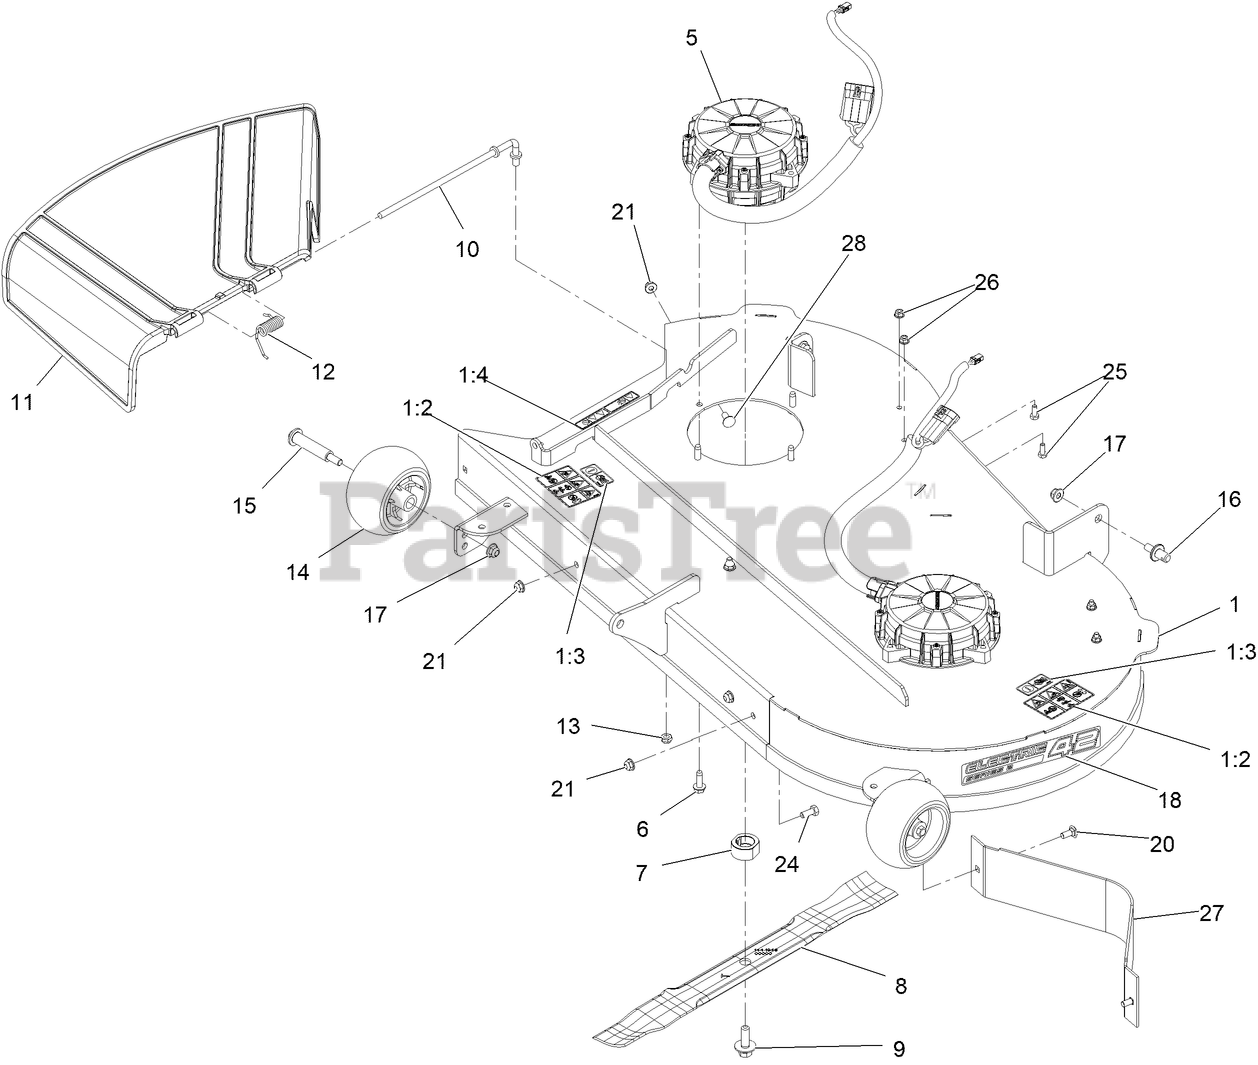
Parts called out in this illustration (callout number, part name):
1	42 In Deck And Decal ASM
1:2	DECAL-DANGER, DECK
1:3	DECAL-NO SPRAY
1:4	Decal-Danger
5	MOTOR-DECK
6	SCREW-THD ROLL, HWH
7	DRIVER-BLADE
8	X-REF TO 144-1948-03
9	Bolt-Blade, Sems
10	ROD-PIVOT
11	DEFLECTOR-DISCHARGE
12	SPRING-TORSION
13	NUT-HEX
14	ROLLER-SCALP, ANTI
15	BOLT-SHOULDER
16	PIN-DECK
17	Nut-HF, NI
18	DECAL-ELECTRIC 42-SERIES 2
20	BOLT-CARR
24	SCREW-HH
25	SCREW-HH
26	SCREW-SHOULDER
27	DEFLECTOR-42
28	BOLT-CARR
